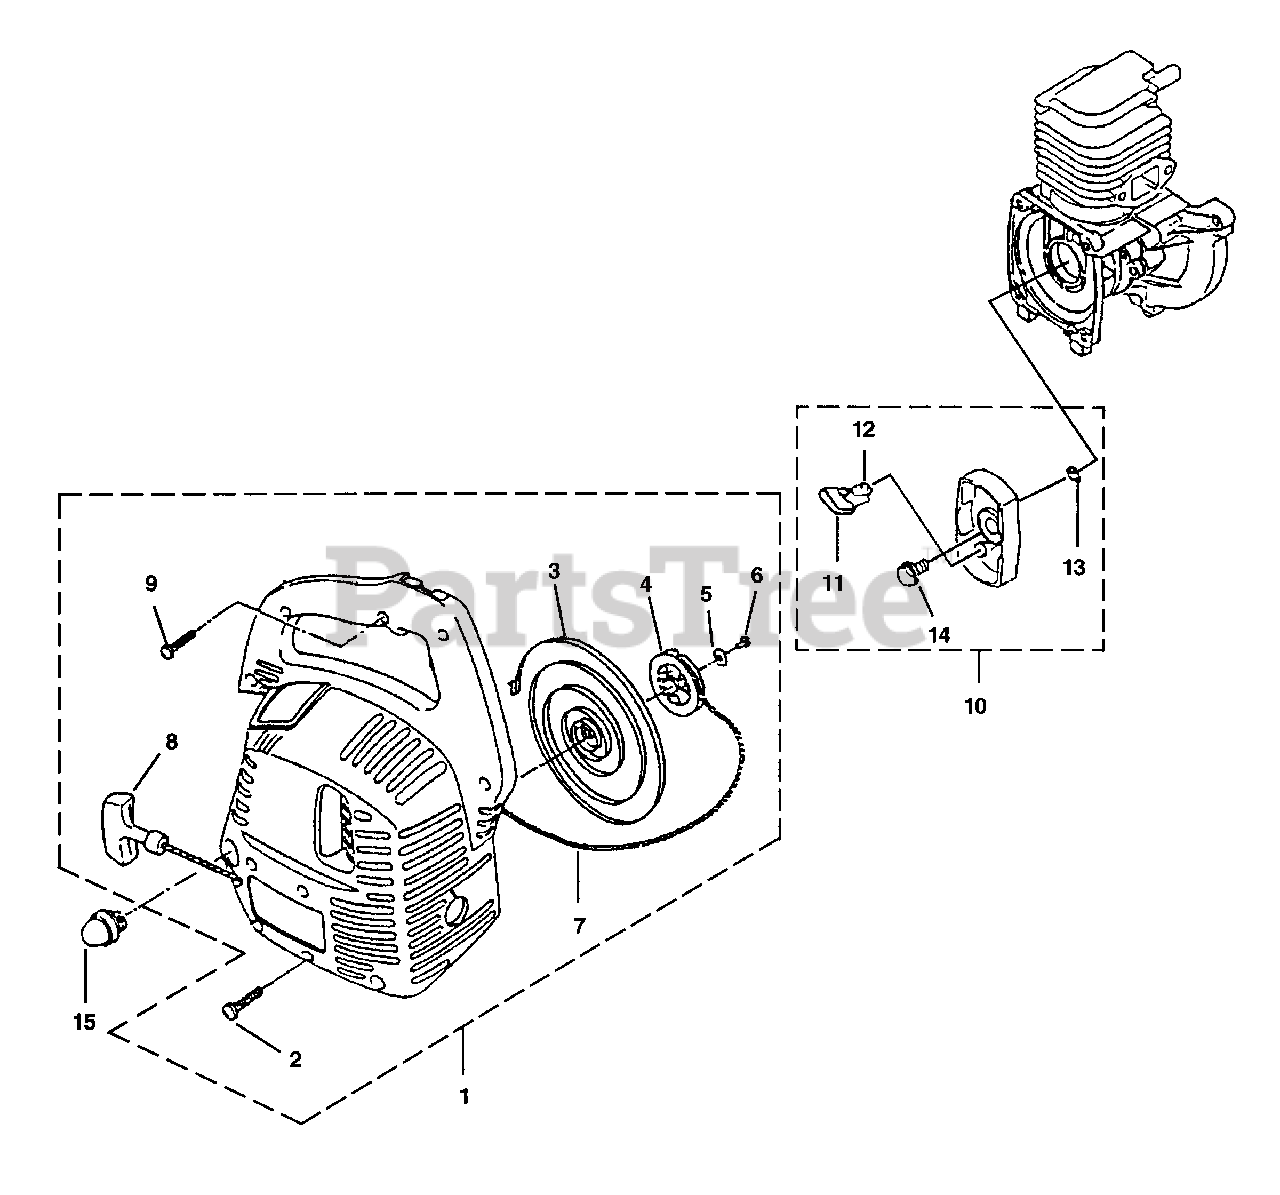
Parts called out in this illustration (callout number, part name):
1	STARTER COMPLETE
2	SCREW-Socket Hd (M5 x 18 W SW)
6	SCREW (M6 x 14)
7	ROPE-Starter
9	SCREW-Tapping (M5 x 20)
10	STARTER CUP ASSEMBLY
12	SPRING-Return
14	BOLT ASSEMBLY (M6 x 14)
15	PRIMER BULB
